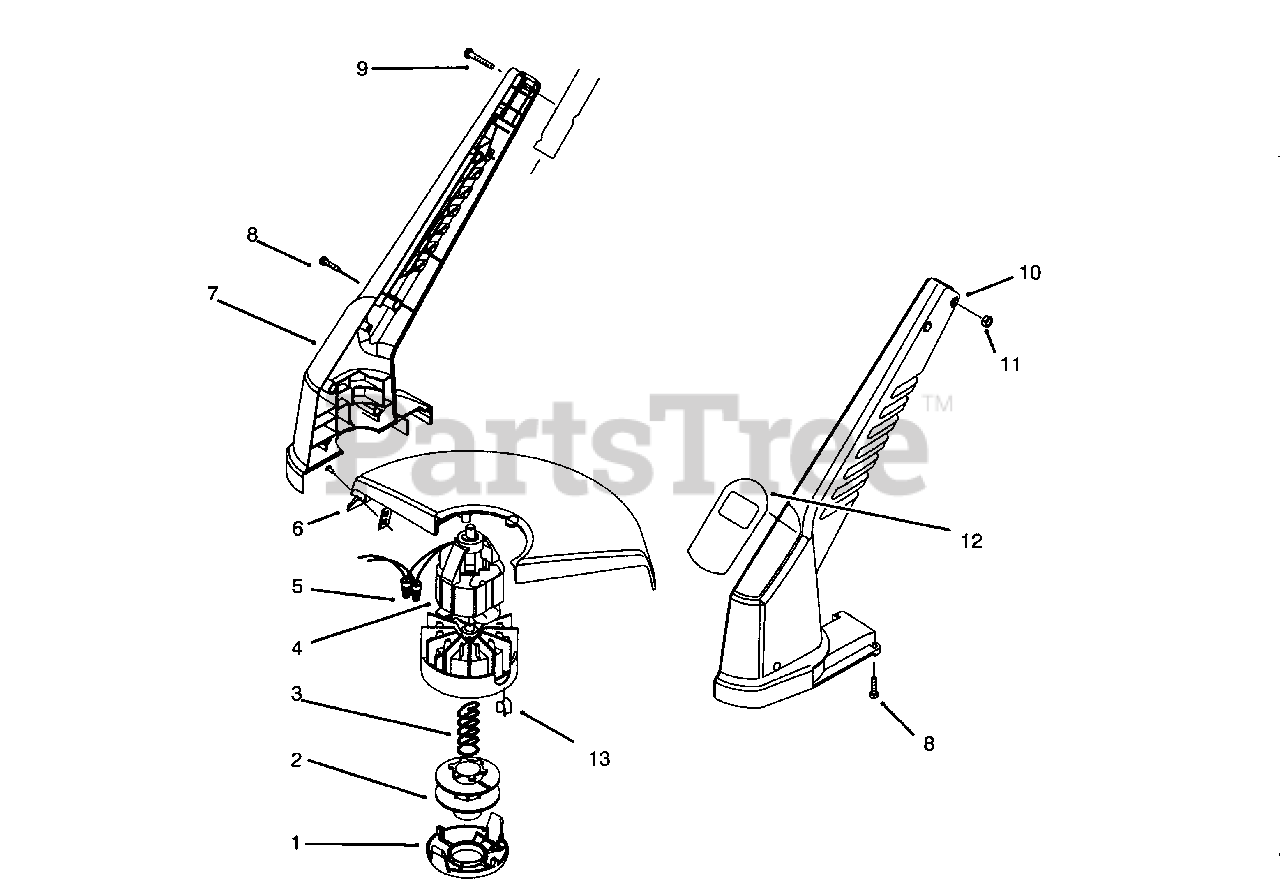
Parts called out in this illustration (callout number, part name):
4	Motor Assembly (Incl. Ret. #13)
5	Connector-Wire Nut
6	Shield-10"
7	Housing R.H.
8	Screw-Pan Hd. Tapping
9	Screw-Pan Hd.
10	Housing L.H.
12	Decal-10" Trimmer
